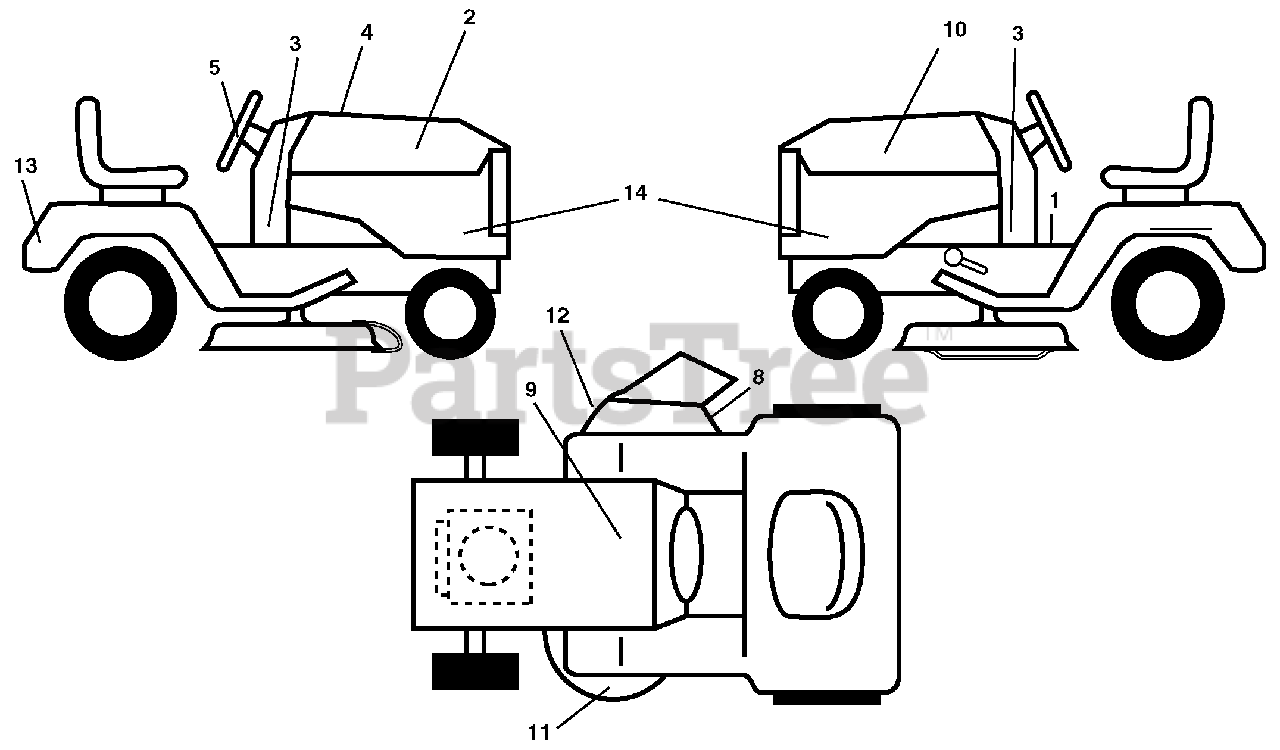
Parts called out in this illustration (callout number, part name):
1	Decal, Operator's
2	Decal, Hood RH
3	Decal, Dash Lower
4	Decal, Replacement
5	Decal, Strg Whl
8	Decal, Mower Sch.
9	Decal, Battery Dnge/Poi
10	Decal, Hood LH
11	Decal, Mower Caution
12	Decal, Mower Warning Keep Hand Away
13	Decal, Fender
14	Decal, Panel SD
14	Decal, Bypass
14	Pad, Footrest, RH
14	Pad, Footrest, LH
14	Manual, Operator's (Eng & French)
14	Manual, Parts
